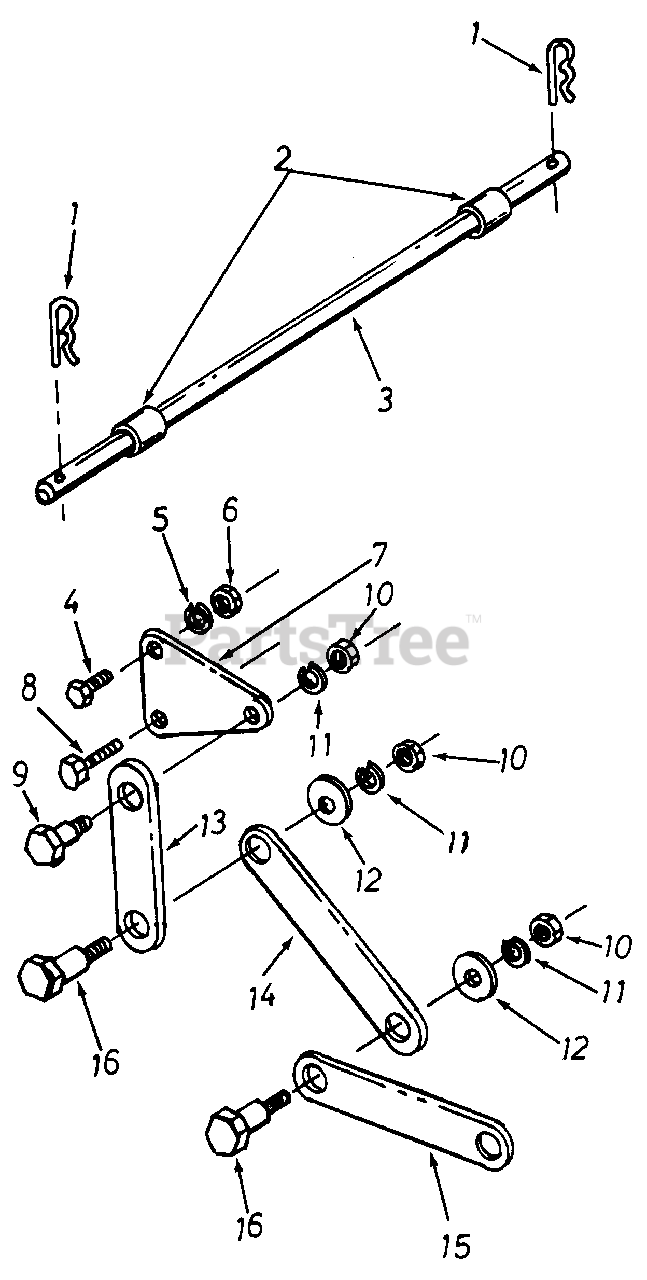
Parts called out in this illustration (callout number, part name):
1	Hair Pin Cotter
3	Tiller Mounting Shaft
4	Hex Bolt 5/16-18 x .75" Lg.
5	L-Wash. 5/16" I.D.
6	Hex Nut 5/16-18 Thd.
7	Tiller Mounting Brkt.
8	Hex Bolt 1/4-20 x .88" Lg.
9	Shoulder Bolt .625" Dia.
10	Hex Nut 3/8-16 Thd.
11	L-Wash. .3/8" I.D.
12	Fl.-Wash.
